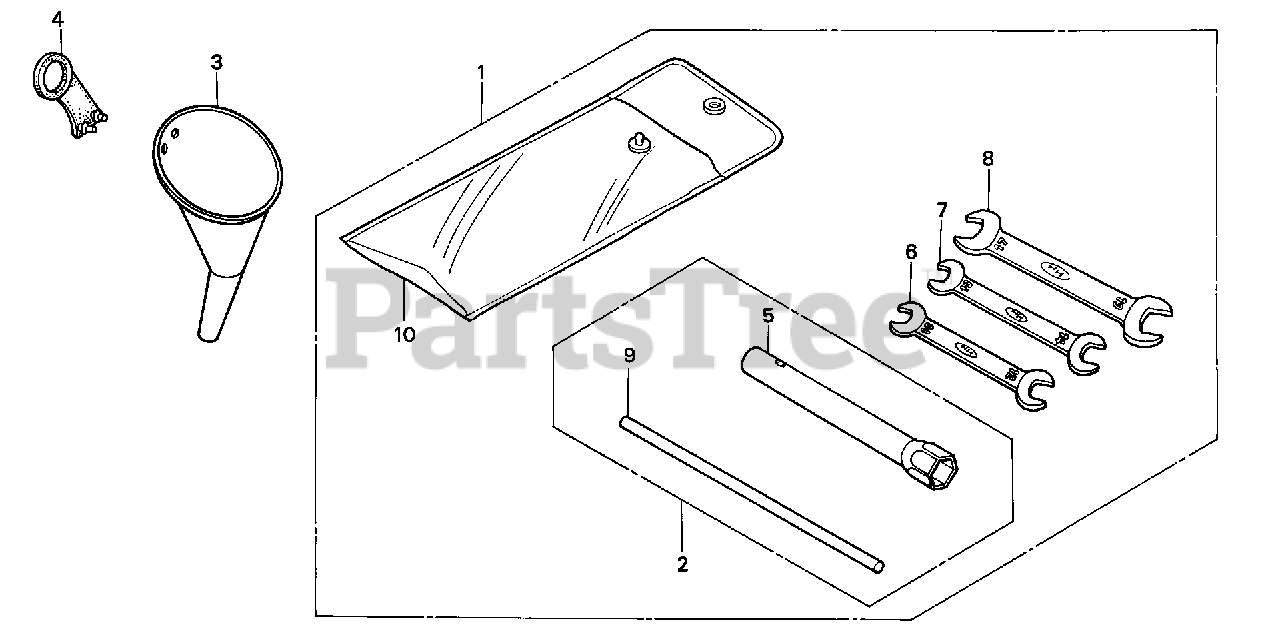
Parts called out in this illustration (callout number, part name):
1	TOOL KIT (N/A: SEE COMPONENTS)
3	FUNNEL, OIL
4	RUBBER, OIL FUNNEL
5	WRENCH, SPARK PLUG (NOT AVAILABLE)
6	WRENCH (10X12) (OPEN END)
7	WRENCH (10X14) (OPEN END)
8	WRENCH (17X19) (OPEN END)
9	BAR A, HANDLE
